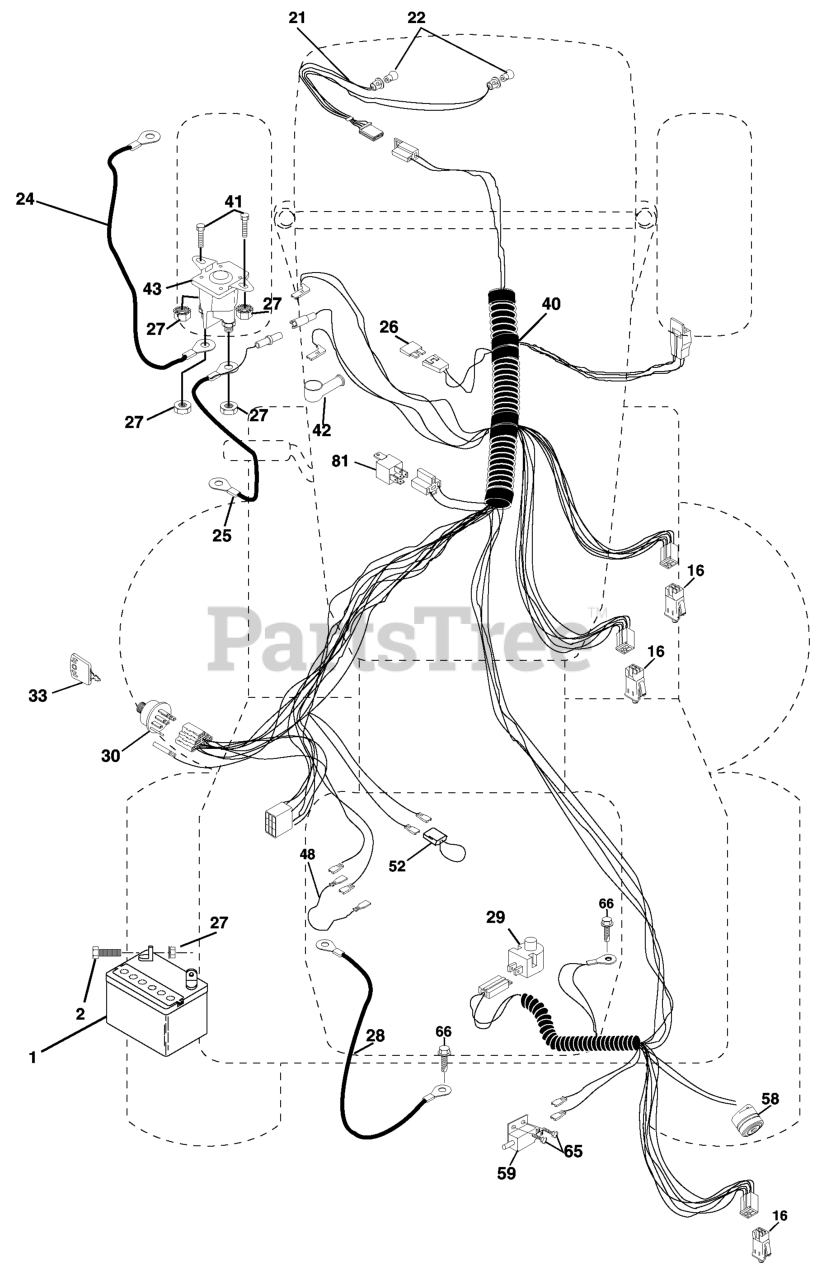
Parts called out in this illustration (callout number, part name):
1	BATTERY 12 VOLT 25 AMP
2	BOLT.HEX.1/4.X.3/4.DICHROMATE
16	SWITCH INTERLOCK
24	BATTERY CABLE GT
25	CABLE BATTERY
26	FUSE 15 AMP
27	NUT
28	CABLE GROUND
29	PLUNGER SWITCH (COLOR:OLIVE)
30	SWITCH IGN
33	KEY MLD GEN DELTA
40	Harness Ign Crd Noram
41	BOLT
42	TERMINAL COVER
43	SOLINOID
48	ADAPTER.AMMETER
52	WIRE PROTECTION LOOP
58	BUZZER
65	Screw Slftp #10-16 x 1/2 Ty-Ab
66	SCREW LT
81	RELAY.ASSY.T
